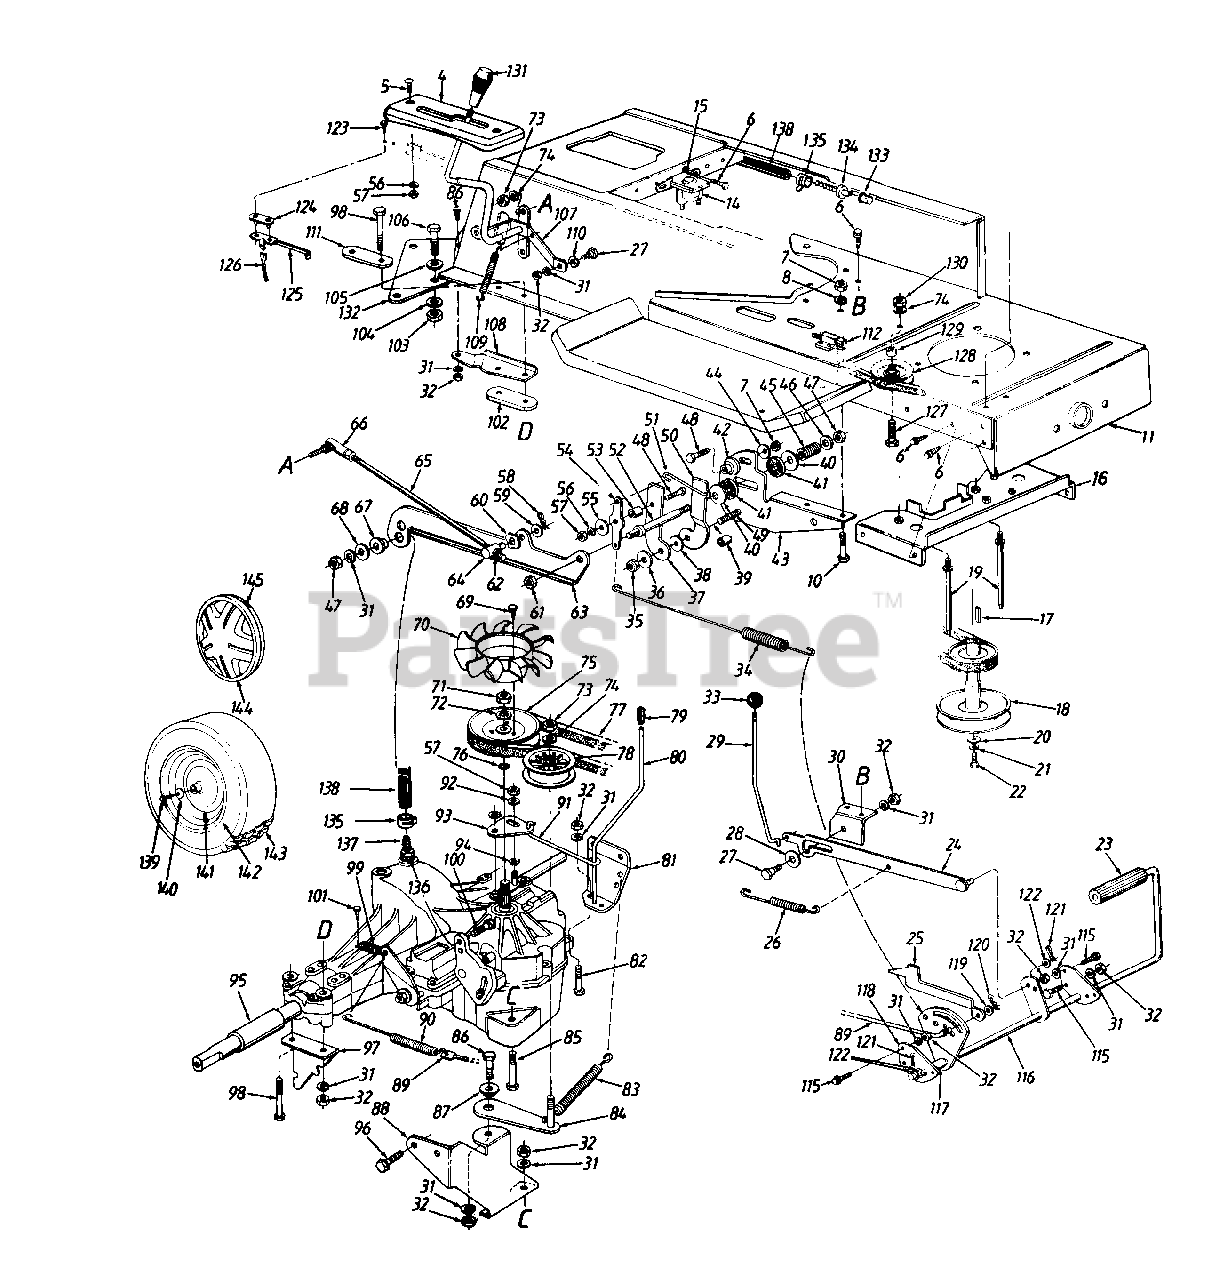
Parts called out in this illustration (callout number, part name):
4	Index Bracket
5	Pan Hd. Mach. Scr. 1/4-20 x .75" Lg.
6	Hex Wash. Hd. TT-Tap Scr. 1/4-20 x .5" Lg.
7	Hex Nut 1/4-28 Thd.
8	L-Wash. 1/4" I.D.
10	Hex . Bolt 1/4-28 x .62" Lg.
11	Lower Frame Ass'y.
14	Solenoid
15	Ext. L-Wash. 1/4" I.D.
16	Belt Guard Brkt. Ass'y.
17	Sq. Key 1/4" x 2" Lg.
18	Engine Pulley
19	Belt Guard Stud 3.6" Lg.
20	Fl-Wash. 7/16" I.D. x 1.25" O.D.
21	L-Wash. 7/16" I.D.
22	Hex Bolt 7/16-20 x 1.5" Lg.
23	Foot Pad
24	Brake Lockout Brkt. Ass'y.
25	Foot Pedal Brkt.
26	Foot Pedal Return Spring
27	Shld. Bolt .437" Dia. x .268"
28	Fl-Wash. 7/16" I.D. x 1-3/8" O.D.
29	Lock-up Rod
30	Bracket
31	L-Wash. 5/16" I.D.
32	Hex Nut 5/16-18 Thd.
33	Ball Knob
34	Neutral Return Spring
35	Hex Nut 5/16-24 Thd.
36	Fl-Wash. .344" I.D. x 1" O.D.
37	Scissor-Flat
38	Fl-Wash. .33" I.D. x 1.25" O.D.
39	Spacer
40	Bell-Wash. .4" I.D. x 1.13" O.D.
41	Friction Washer
42	Centering Gauge Spacer
43	Neutral Return Mtg. Brkt.
44	Bell-Wash. .265" I.D. x .75" O.D.
45	Comp. Spring 1.19" Lg.
46	Fl-Wash. .312" I.D. x .75" O.D.
47	Hex Nut 5/16-24 Thd.
48	Hex Bolt 1/4-28 x 1" Lg. (Gr. 5)
49	Rib Neck Bolt 5/16-24 x .84" Lg.
50	Scissor-Offset
51	Neutral Return Rod
52	Friction Disc Stud
53	Shld. Spacer
54	Neutral Return Lever
55	Fl-Wash. .265" I.D. x 1" O.D.
56	L-Wash. 1/4" I.D.
57	Hex Nut 1/4-20 Thd.
58	Hairpin Clip
59	Fl-Wash. .375" I.D. x .87" O.D.
60	Spring Wash. .39" I.D.
61	Hex L-Nut 3/8-24 Thd.
62	Hex Jam Nut 3/8-24 Thd.
63	Neutral Return Brkt.
64	Ferrule 3/8-24 Thd.
65	Control Rod
66	Ball Joint 3/8-24 Thd.
67	Shld. Spacer .5" Dia. x .27" Lg.
68	Fl-Wash. .349" I.D. x .879" O.D.
69	Hex Wash. Hd. Tap Scr. #12 x 3/8" Lg.
71	Hex Nut 1/2-20 Thd.
72	L-Wash. 1/2" I.D.
73	Hex Nut 3/8-24 Thd.
74	L-Wash. 3/8" I.D.
75	Transmission Pulley
76	Wire Ring
77	V - Belt
78	Fl-Idler Pulley 2.75" O,D.
79	Rod End Grip
80	Bypass Control Lever
83	Ext. Spring 6.12
86	Hex Bolt 5/16-18 x .75" Lg.
87	Shld. Spacer .5" Dia. x .27" Lg.
88	Transaxle Support Brkt. - R.H.
89	Brake Rod 24.94" Lg.
90	Ext. Spring
91	Bypass Actuator Rod
92	Fl-Wash. .281" I.D. x .5" O.D.
93	Bypass Adjustment Brkt.
94	External L-Wash. 1/4" I.D.
95	Sleeve .758" I.D. x 1" O.D.
96	Hex . Wash. TT-Tap Scr. 5/16-18 x .62" Lg.
97	Retainer Brkt. - Transaxle
98	Hex Bolt 5/16-18 x 3.5" Lg. (Gr. 5)
99	Tension Spring
100	Hex Bolt 5/16-24 x 1" Lg. (Special)
101	Hex Wash. Hd. AB-Tap Scr. #10 x .5" Lg.
102	Transaxle Spacer
103	Hex Nut 7/16-14 Thd. (Gr. 5)
104	Fl-Wash. .469" I.D. x .875" O.D.
105	Bell-Wash. .46" I.D. x 1.13" O.D.
106	Hex Bolt 7/16-14 x 1" Lg.
107	Speed Control Lever Ass'y.
108	Axle Support Brkt. - R.H.
108	Axle Support Brkt. - L.H.
109	Ext. Spring 2.75" Lg.
110	Spr-Wash. .445" I.D. x .75" D.D.
111	Transaxle Mtg. Brkt.
112	Safety Switch (Clutch)
115	Hex Wash. TT-Tap Scr. 5/16-18 x .75" Lg.
118	Pedal Bracket
119	Fl-Wash. .344" I.D. x .62" O.D.
120	Cotter Pin 3/32" Dia.
121	Cotter Pin 1/8" Dia.
122	Fl-Wash. .64" I.D. x .94" O.D.
123	Hex Wash. Hd. AB-Tap Scr. #8 x .5" Lg.
124	Insulator Nut Plate
125	Reverse Safety Switch
126	Extension Wire
127	Hex Bolt 3/8-16 x 1.5" Lg. (14 H.P. OHV Only)
128	Idler Pulley
129	Fl-Wash. .39" I.D.
130	Hex Nut 3/8-16 Thd.
131	Shift Knob
132	Hitch Plate Extension
133	Vent Cap
134	Plastic Vent
135	Clamp
136	O - Ring
137	Hose Fitting
138	Fuel Line 18" Lg.
139	Hex Bolt 5/16-24 x .75" Lg.
140	Bell-Wash. .345" I.D. x .88" O.D.
141	Air Valve
145	Spring Clip
